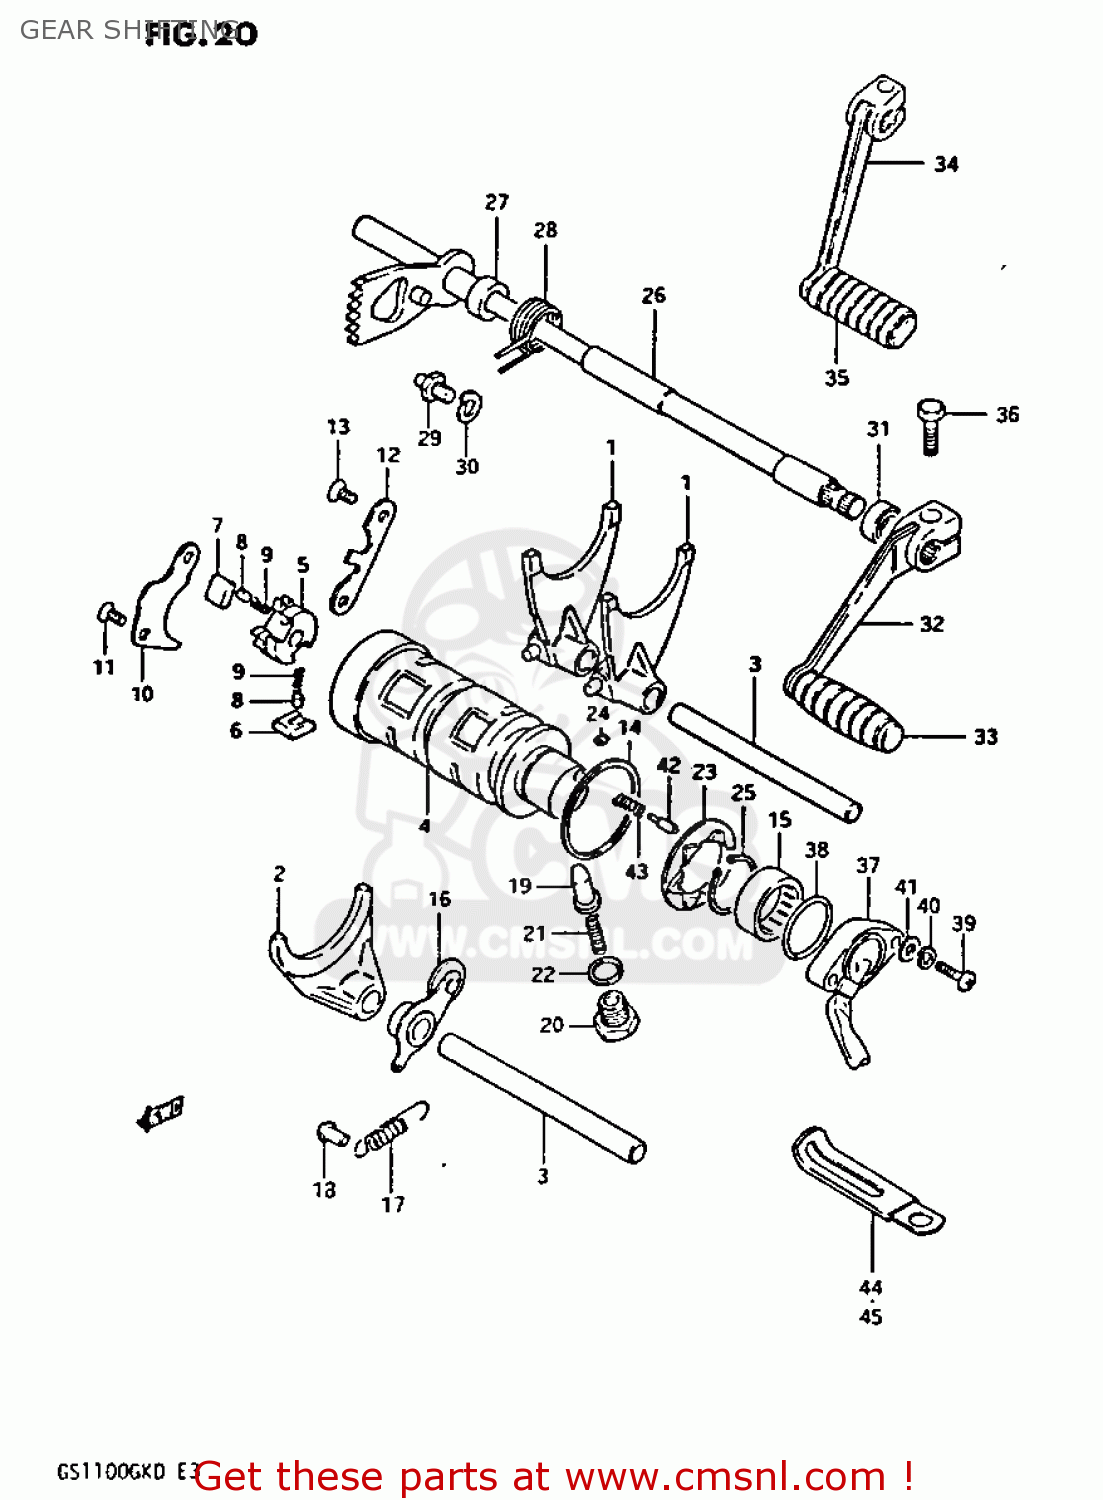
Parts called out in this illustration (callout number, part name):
1	FORK,GEAR SHIFT NO.1
2	FORK,GEAR SHIFT NO.3
3	SHAFT,GEAR SHIFT FORK
4	CAM,GEAR SHIFT
5	GEAR,GEARSHIFT CAM DRIVE
6	PAWL,GEAR SHIFT NO.1
7	PAWL,GEAR SHIFT NO.2
8	PIN(5X8)
9	SPRING
10	LIFTER,GEAR SHIFT PAWL
11	SCREW
12	GUIDE,GEAR SHIFT CAM
13	SCREW
14	WASHER(40X45X1)
15	BEARING(25X32X12)
16	STOPPER,GEAR SHIFTING
17	SPRING
18	RIVET
19	STOPPER,GEAR SHIFT CAM NO.2
20	HOLDER,GEAR SHIFT CAM STOP SPR
21	SPRING
22	GASKET(14X19.2X2) (NAS)
23	PLATE,GEAR SHIFT CAM STOPPER
24	PIN 4X6
25	CIRCLIP
26	SHAFT,GEAR SHIFT
27	SPACER (12X20X12)
28	SPRING
29	STOPPER,GEAR SHIFT CAM
30	WASHER,LOCK
31	OIL SEAL
32	LEVER ASSEMBLY,GEAR SHIFTING
33	RUBBER,GEAR SHIFT PEDAL
34	LEVER ASSEMBLY,GEAR SHIFTING
35	RUBBER,PEDAL
36	BOLT
37	TERMINAL BASE ASSY,GEAR SHIFT
38	O-RING (D:2.4 ID:26.2)
39	SCREW 5X20
40	LOCK WASHER
41	WASHER
42	PIN(5X15.5)
43	SPRING
44	CLAMP L:35
45	CLAMP
